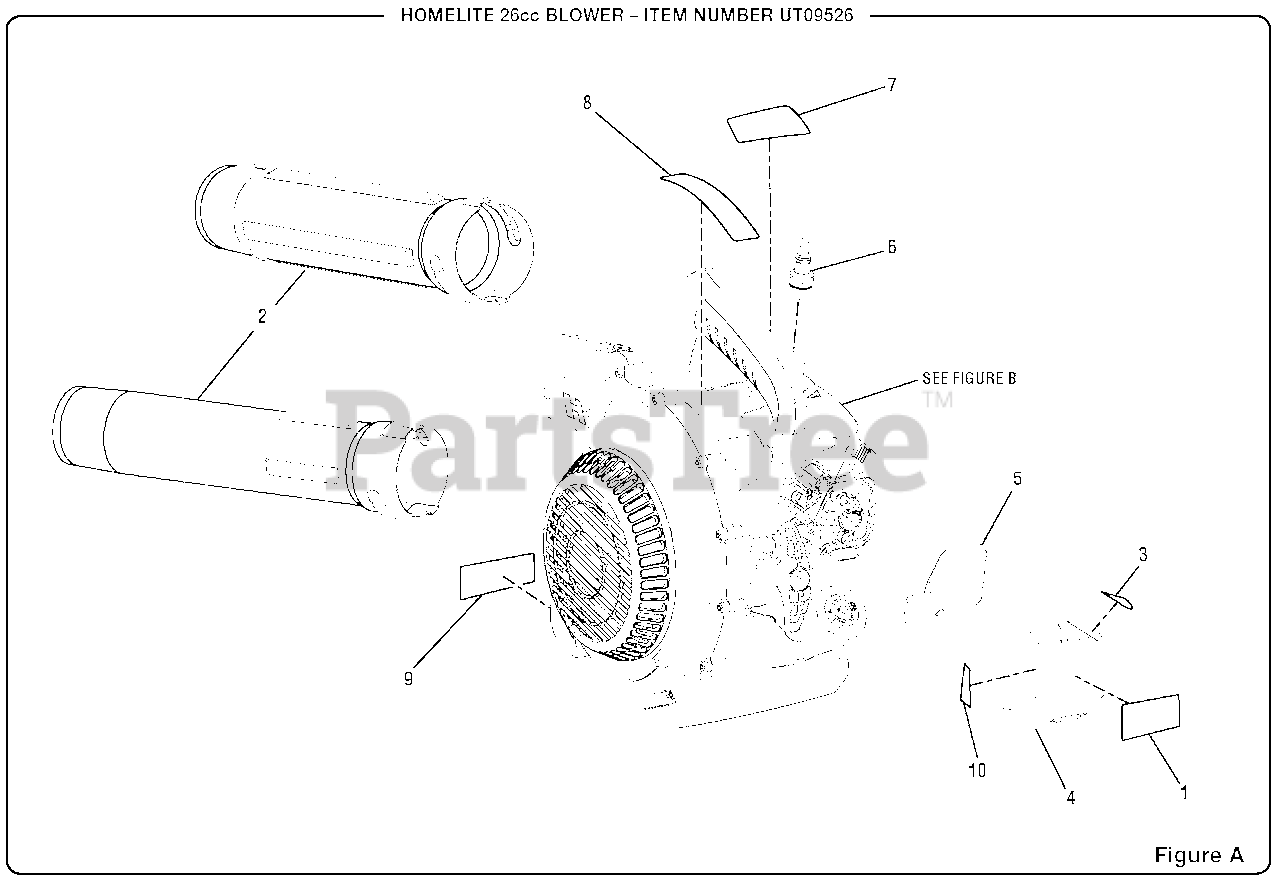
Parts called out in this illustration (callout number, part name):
1	Starting Instructions Label
2	Sweeper Nozzle & Upper Blower Tube Assembly
3	Throttle Label
4	Air Box Cover w/Label
5	Air Box Gasket
6	Spark Plug (L7RTC)
7	Logo Label (Engine Shroud)
8	Warning Icon Label
9	Combustion Warning Label
10	Choke Label
